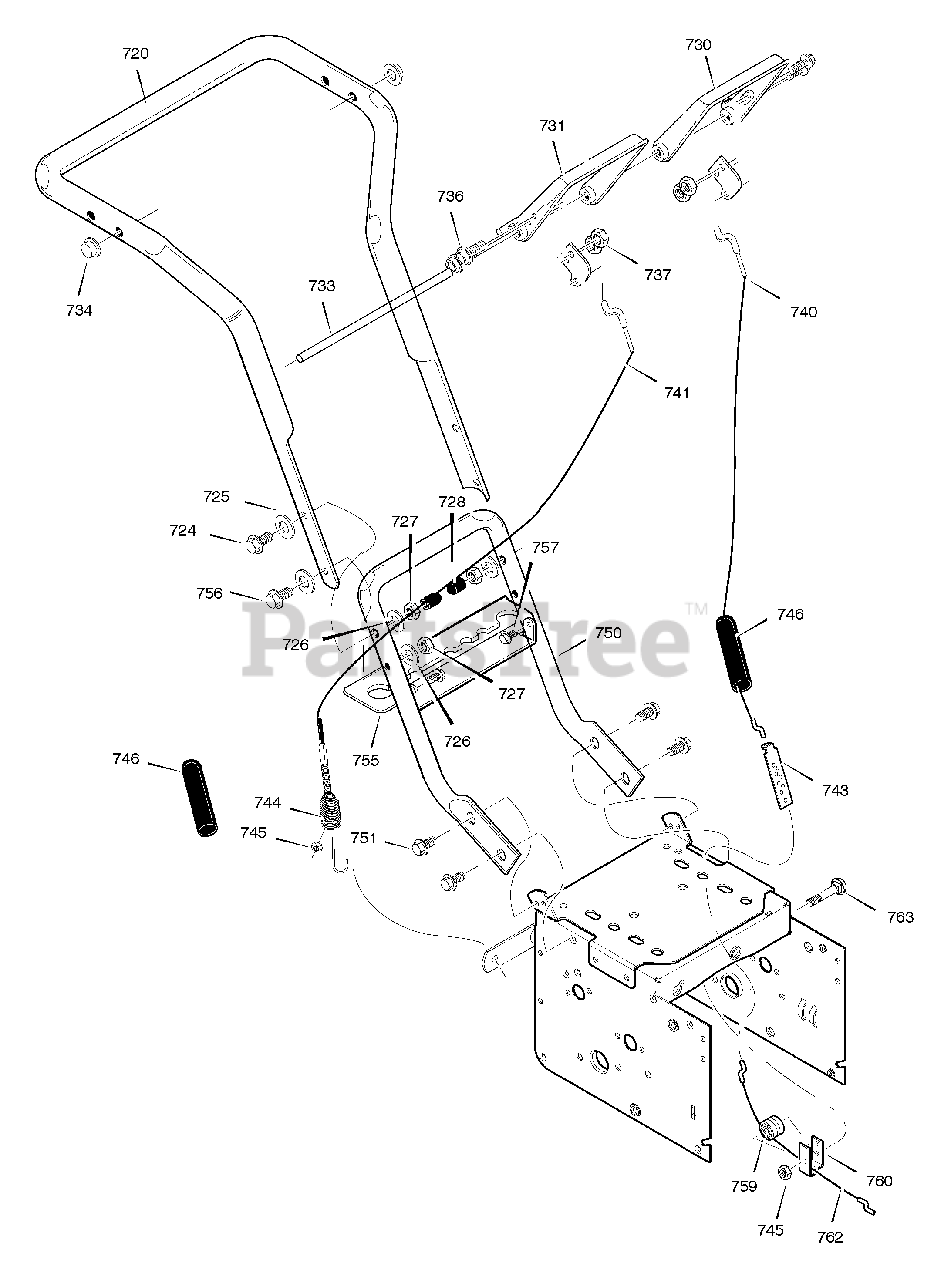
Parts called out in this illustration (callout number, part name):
725	WASHER, FLAT
726	WASHER, SPLIT
727	NUT
728	PLASTIC-STOP
730	CLUTCH, LEFT HANDLE CONTROL
731	CLUTCH, RIGHT HANDLE CONTROL
733	ROD, PIVOT HANDLE
734	PUSH ON CAP
735	PLATE, CABLE PIVOT
737	NUT
740	CABLE, CLUTCH
741	CABLE, AUGER CLUTCH
743	BRKT, CABLE ADJUST
744	SPRING, AUGER CLUTCH
745	LOCKNUT
746	BOOT, CLUTCH SPRING
750	HANDLE, LOWER
751	SCREW 5/16-18 x 0.75
752	WASHER
755	BRACKET, GEAR SELECTOR
756	SCREW 5/16-18 x 2
757	SCREW, 1/4-20 x 0.63
759	SPOOL-CABLE, AUGRT CLUTCH
760	BRACKET, CABLE SPOOL YZ
762	CABLE, LOWER DRIVE 12"
763	BOLT, HEX 1/4-20 x 1.50 YZ
